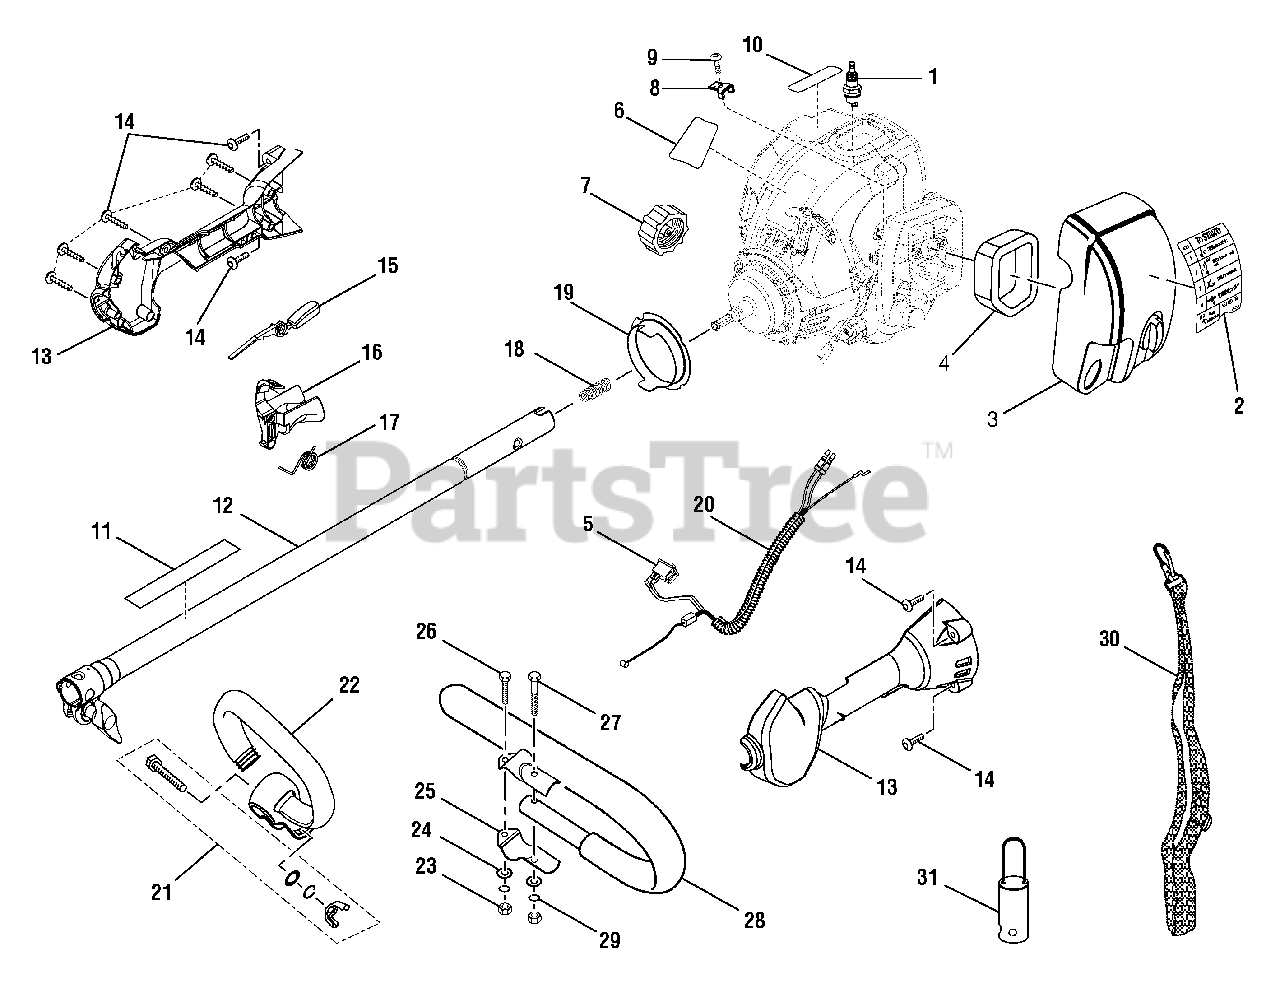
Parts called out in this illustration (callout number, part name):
1	SPARK PLUG (CHAMPION RCJ6Y OR NGK BPMR7)
2	STARTING/PRIMER LABEL
3	AIR BOX COVER
4	AIR FILTER
5	SWITCH (MOMENTARY CONTACT)
6	MODEL LABEL (CS30)
8	THROTTLE CABLE CLIP (CS30 AND SS30)
9	SCREW (M4 X 16 mm TORX PAN HD.)
10	LOGO PLATE
11	WARNING DECAL (CS30 AND SS30)
12	BOOM ASSEMBLY (CS30 AND SS30)
13	HANDLE ASSEMBLY
14	HANDLE SCREW (10-14 X 1 in. TORX T.F.)
15	TRIGGER LOCK
18	COMPRESSION SPRING
19	RING GUARD
20	THROTTLE CABLE ASSEMBLY
21	FASTENER KIT (CS30 AND SS30)
22	"D" HANDLE (CS30 AND SS30)
23	HEX NUT (1/4-20) (BC30)
24	WASHER (BC30)
25	HANDLE BAR CLAMP (BC30)
26	SCREW (1/4-20 X 1 in. HEX CAP)(BC30)
27	BOLT (1/4-20 X 1-1/2 in. HEX HD.) (BC30)
28	"J" HANDLE AND GRIP (BC30)
29	LOCK WASHER (BC30)
30	SHOULDER STRAP (BC30)
31	HANGER CAP
